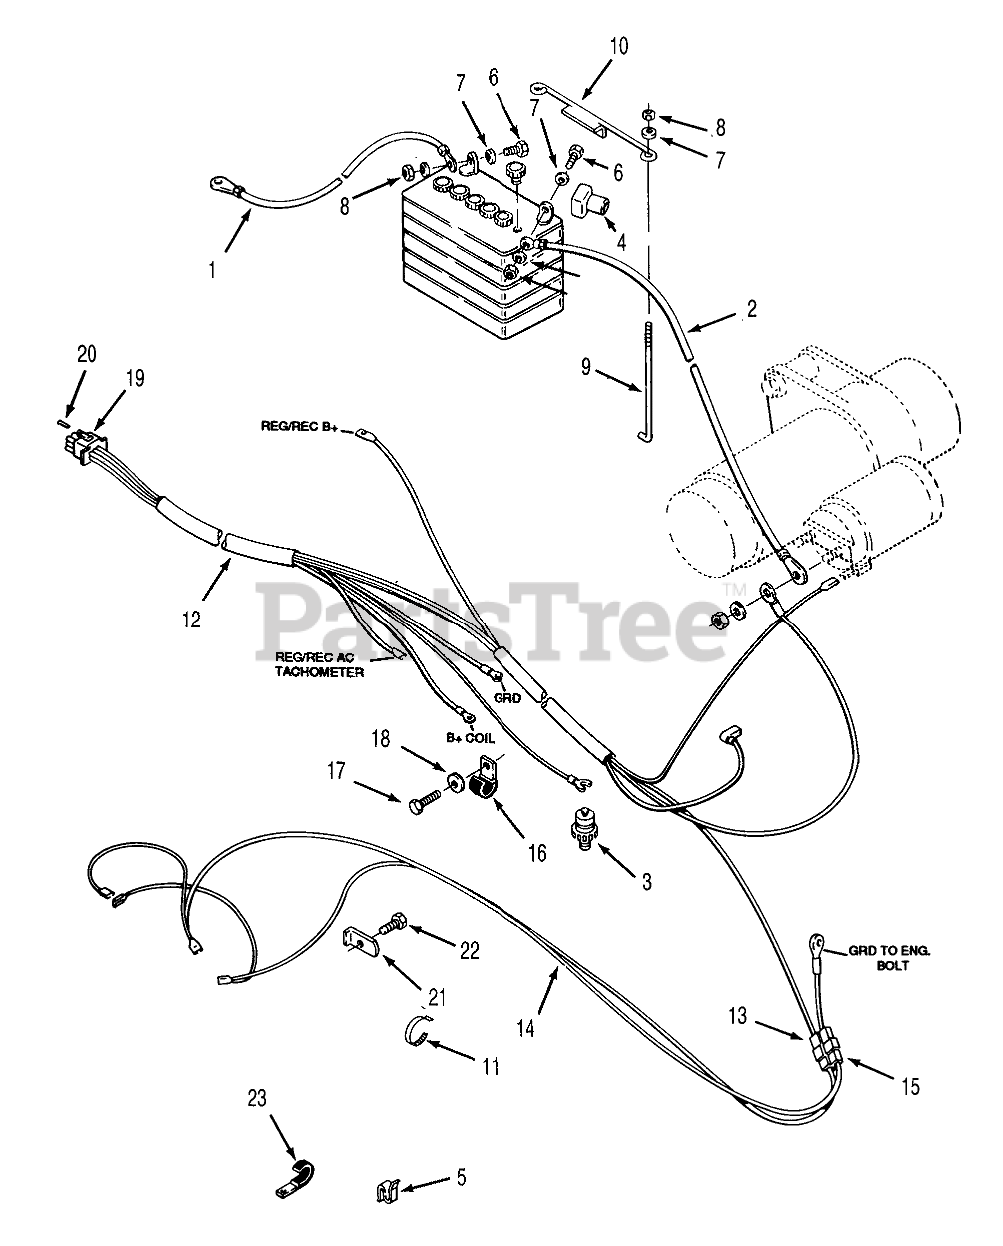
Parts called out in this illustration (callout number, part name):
1	ASS'Y-WIRE
2	SHIELD-SD DISCHARGE
3	LOW OIL PRESSURE
4	Boot
5	SPEED CLIP
6	Bolt
8	Nut
9	Hook-Battery Hold Down
10	HOLDDOWN-BATTERY
11	PLASTIC TIE
12	Engine Wiring Harness
13	MALE CONNECTOR
14	HARNESS-HEADLIGHT
15	CONNECTOR BODY
16	Clip
17	Bolt
18	LOCKWASHER 1/4 IT
19	CONNECTOR CAP
20	CONTACT SOCKET
21	LOCK-HEADLIGHT
22	Bolt
23	CLIP
